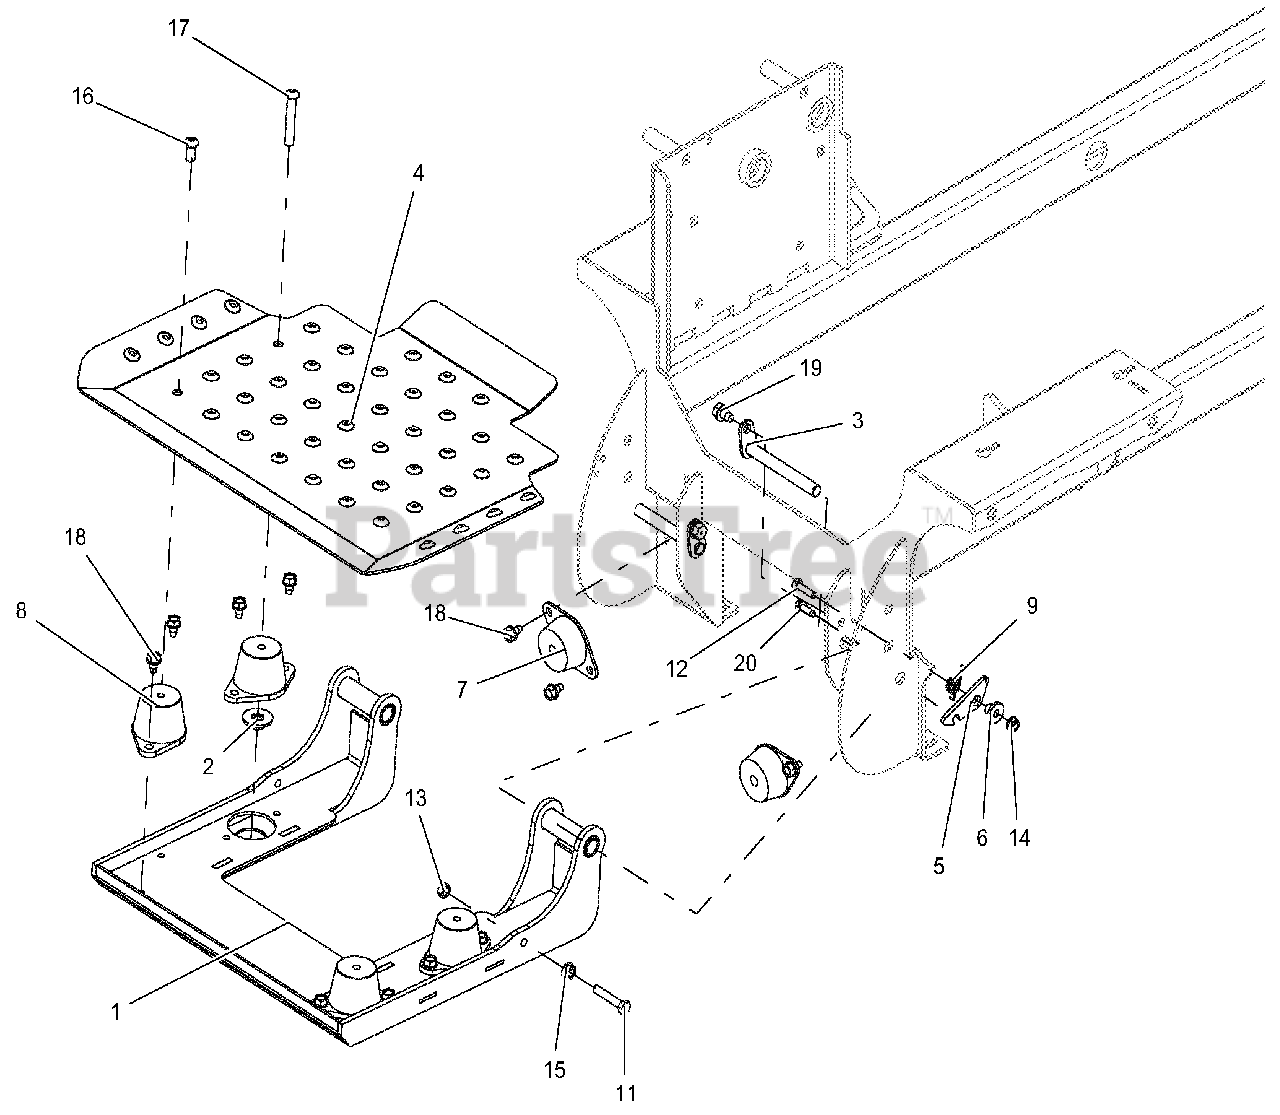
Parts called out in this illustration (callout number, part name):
1	WLDMT, PLATFORM CARRIER
2	WLDMT, SEAT RETAINER
3	WLDMT, PIN
4	PLATE, OPERATOR PLATFORM-RED
5	LATCH, PLATFORM
6	BSHG, FLANGE .26 X .42 X .88 X .33
7	MOUNT, ENGINE. VIBRATION ISO
8	MOUNT, ISOLATOR
9	SPRG, TORSION
11	BLT-HEX .31-18X1.75 GR5 YWZC
12	BLT-HEX .25-20X1.00 GR5 YWZC
13	NUT-LK-CTR .31-18 YWZ C
14	NUT-LK-NYL-FLG .25-20 YWZC
15	@ NUT-SPNLK-FLG .312-18 YWZC
16	SCR-BTHD-SOCKET .38-16X.75 YWZC
17	SCR-BTHD-SOCKET .38-16X2.25 FTH YWZC
18	SCR-TAP .31-18X.50 HWH TR YW Z
19	SCR-TAP .38-16X.50 HWH TR YW Z
20	SCR-TAP .25-20X.75 HWH TR YW Z
